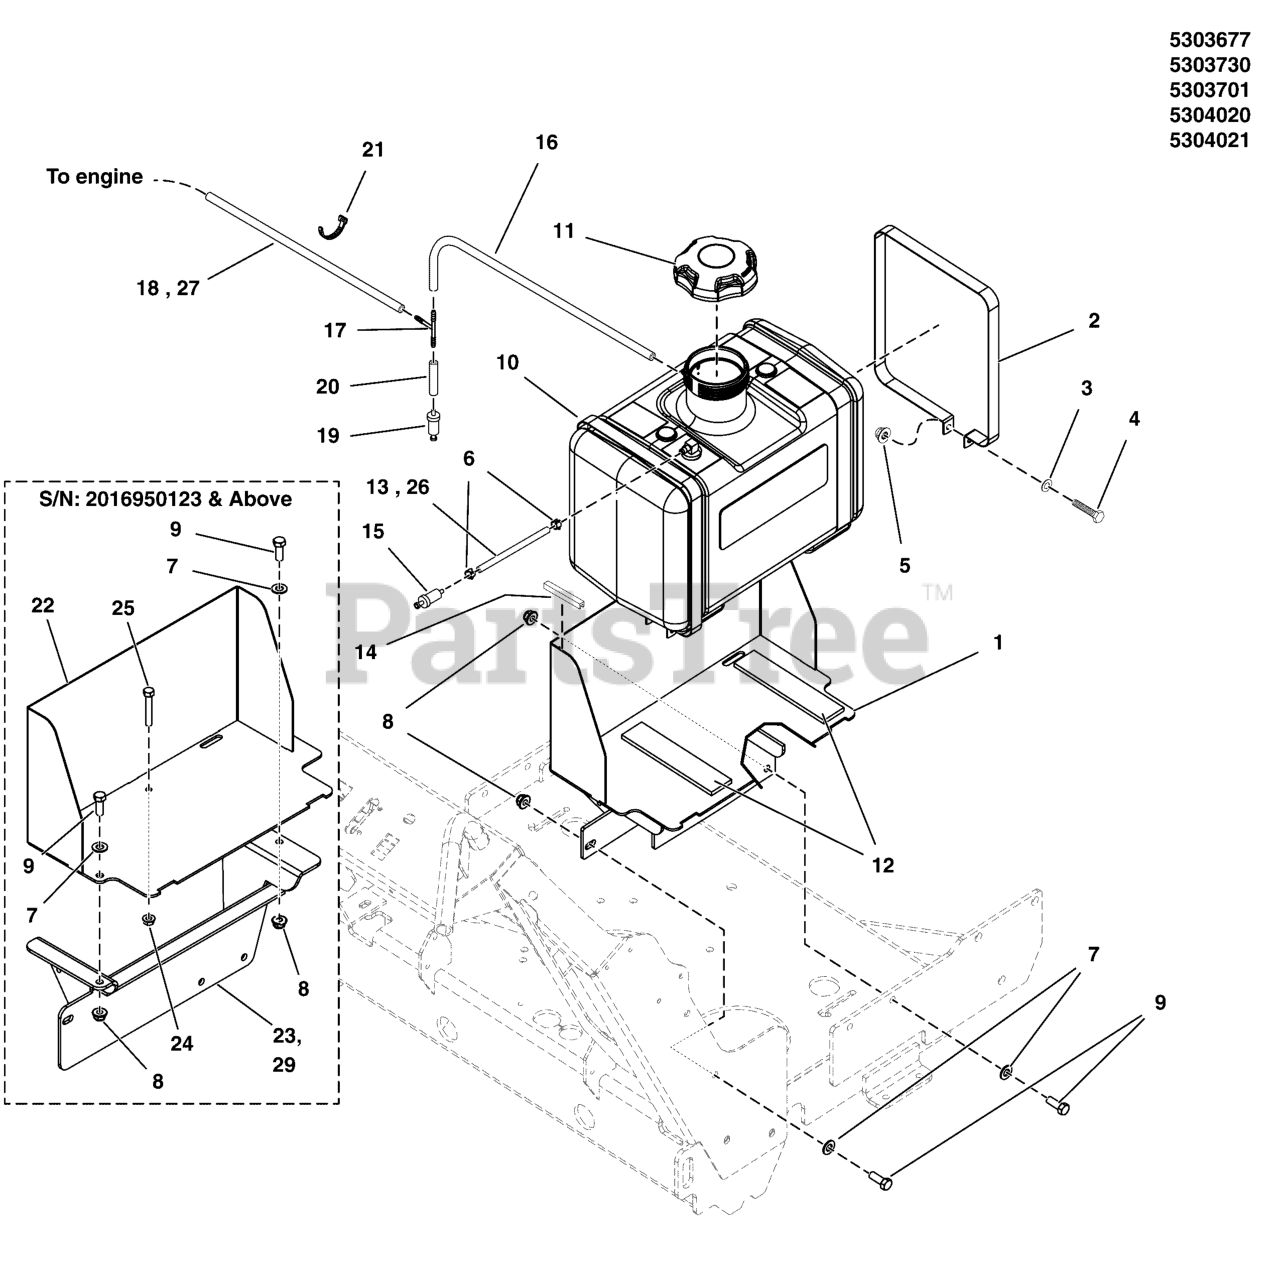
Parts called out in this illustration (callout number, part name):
1	WELD, FUEL TANK MOUNT, WALK - BLK
2	STRAP, FUEL TANK
3	WASHER, 1/4 SAE
4	BOLT, 1/4-20 X 1-1/4, GD5
5	NUT, 1/4-20 HEX NYLOCK FLANGE
6	CLAMP, HOSE, EXTERNAL, 1/2 - RED
7	WASHER, 3/8 SAE
8	NUT, 3/8-16 HEX NYLOCK FLANGE
9	BOLT, 3/8-16 X 1" GD5 CZ
10	TANK, 5 GAL, W DROP TUBE/VENT
11	FUEL CAP, 3-1/2", MANAGED VENT OUT, 12"
12	PAD, RUBBER MOUNT
13	HOSE, 1/4" FUEL, 12.00"
14	BODY MOLDING, 1.25" LONG
15	FUEL FILTER
16	HOSE, VAPOR, 5MM ID, 15.50 LG
17	FITTING, 3/16" TEE, BARB TYPE, HDPE
18	HOSE, VAPOR, 5MM ID, 8.00 LG
19	FILTER, FUEL
20	HOSE, VAPOR, 5MM ID, 4.50 LG
21	TIE,SELF-LOCKING, 6"
22	WELD, FUEL TANK MOUNT UPPER, W35 - BLK
23	WELD, FUEL TANK MOUNT LOWER, W35 - BLK
24	NUT, 5/16-18 HEX SERRATED FLANGE (SMALL)
25	BOLT, 5/16-18 X 2 ALL THD
26	HOSE, 1/4" FUEL, 29.50"
27	HOSE, VAPOR, 5MMID, 20.50 LG
28	GROMMET
29	WELD, FUEL TANK, MOUNT, LOWER, W35 - BLK
